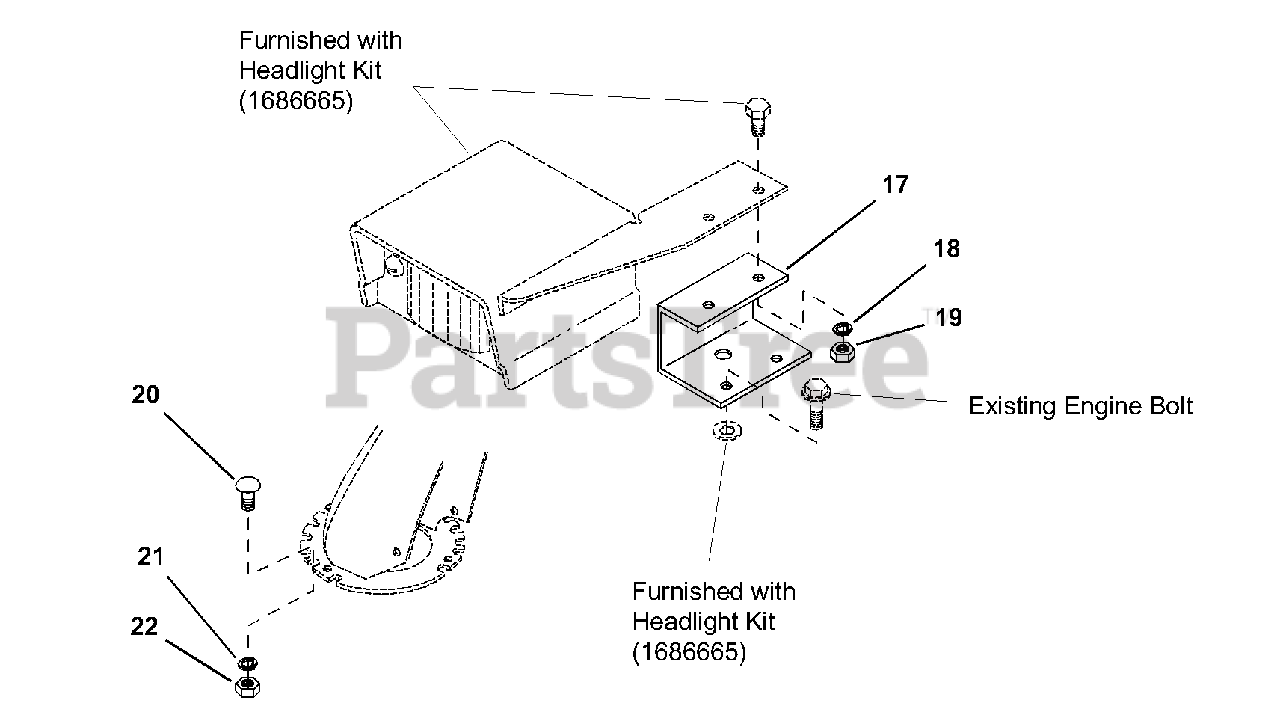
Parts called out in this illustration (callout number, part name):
17	BRACKET, Headlight Adapter
18	LOCKWASHER, 5/16
19	NUT, Hex, 5/16-18
20	BOLT, Carriage, 1/4-20 x 1/2
21	LOCKWASHER, 1/4
22	NUT, Hex, 1/4-20
